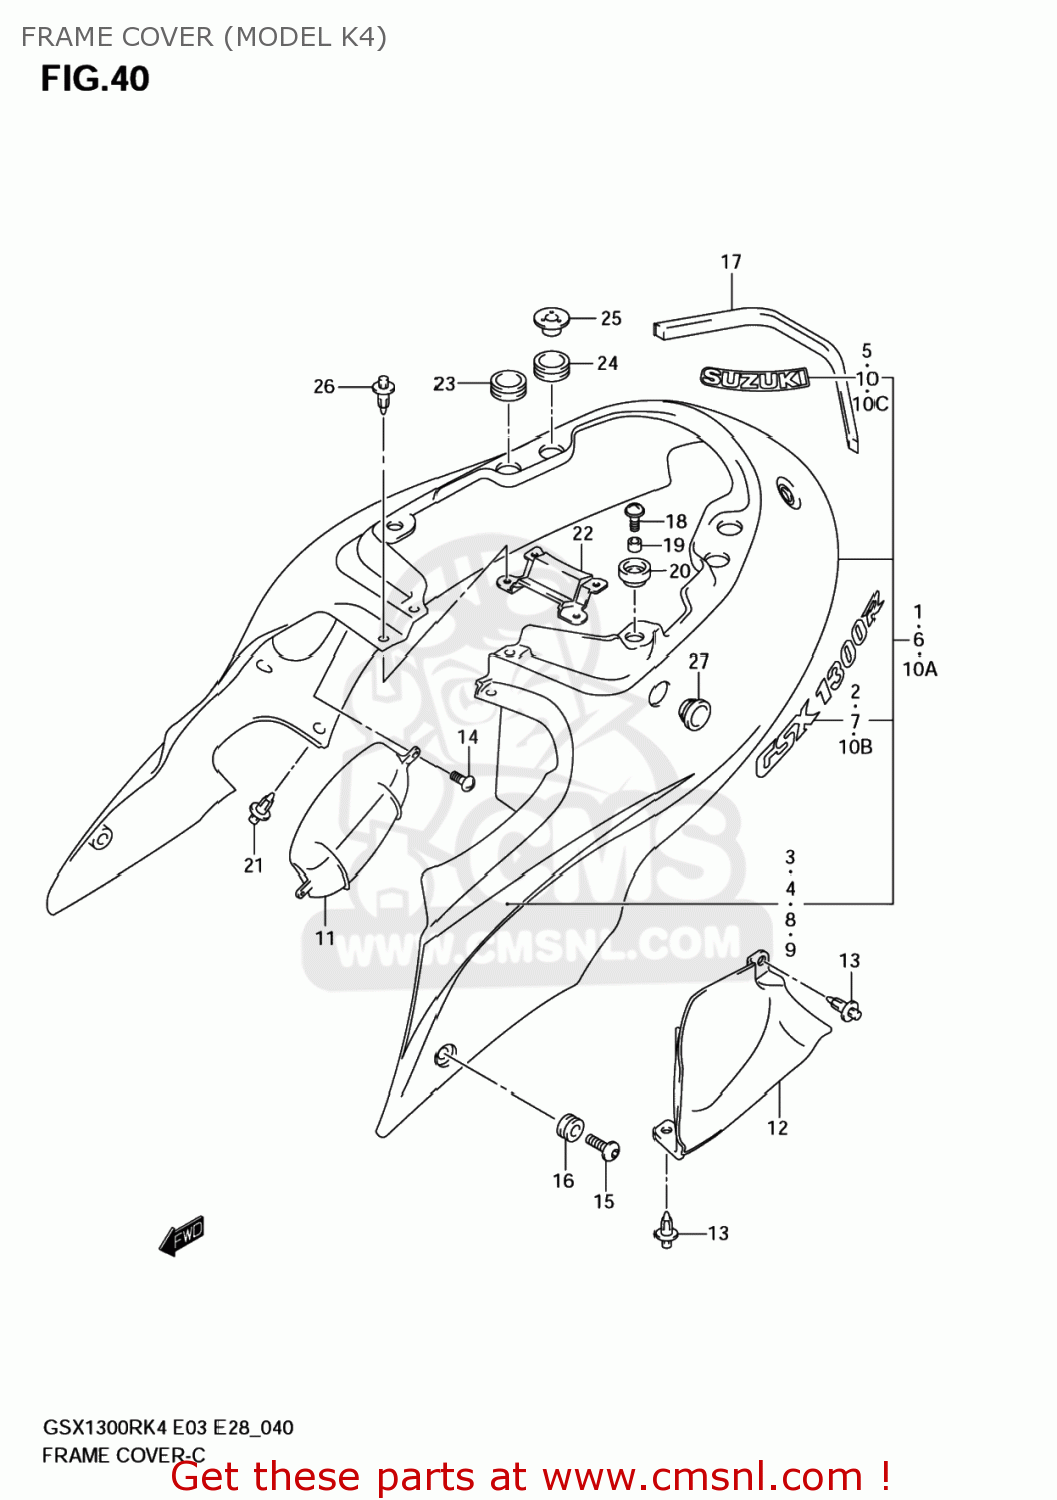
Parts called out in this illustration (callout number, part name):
1	COVER,FRAME(SILVER)
2	EMBLEM,FRAME COVER
3	TAPE,FRAME COVER,R(BLUE)
4	TAPE,FRAME COVER,L(BLUE)
5	EMBLEM,SUZUKI
6	COVER,FRAME(BLUE)
7	EMBLEM,FRAME COVER
8	TAPE,FRAME COVER,R(BLACK)
9	TAPE,FRAME COVER,L(BLACK)
10	EMBLEM,SUZUKI
10A	COVER,FRAME(RED)
10B	EMBLEM,FRAME COVER
10C	EMBLEM,SUZUKI
11	CAP,FRAME COVER HOLE,R
12	CAP,FRAME COVER HOLE,L
13	CLIP(BLACK)
14	SCREW
15	SCREW(6X20)
16	CUSHION
17	CUSHION,FRAME COVER UPR
18	SCREW(6X20)
19	SPACER(6.5X10X11)
20	CUSHION
21	CLIP(BLACK)
22	COVER,FRAME CTR
23	CUSHION,FRAME COVER UPR RR
24	CUSHION,FRAME COVER UPR RR RR
25	WASHER,FRAME C
26	CLIP(BLACK)
27	CUSHION,FRAME COVER CTR
